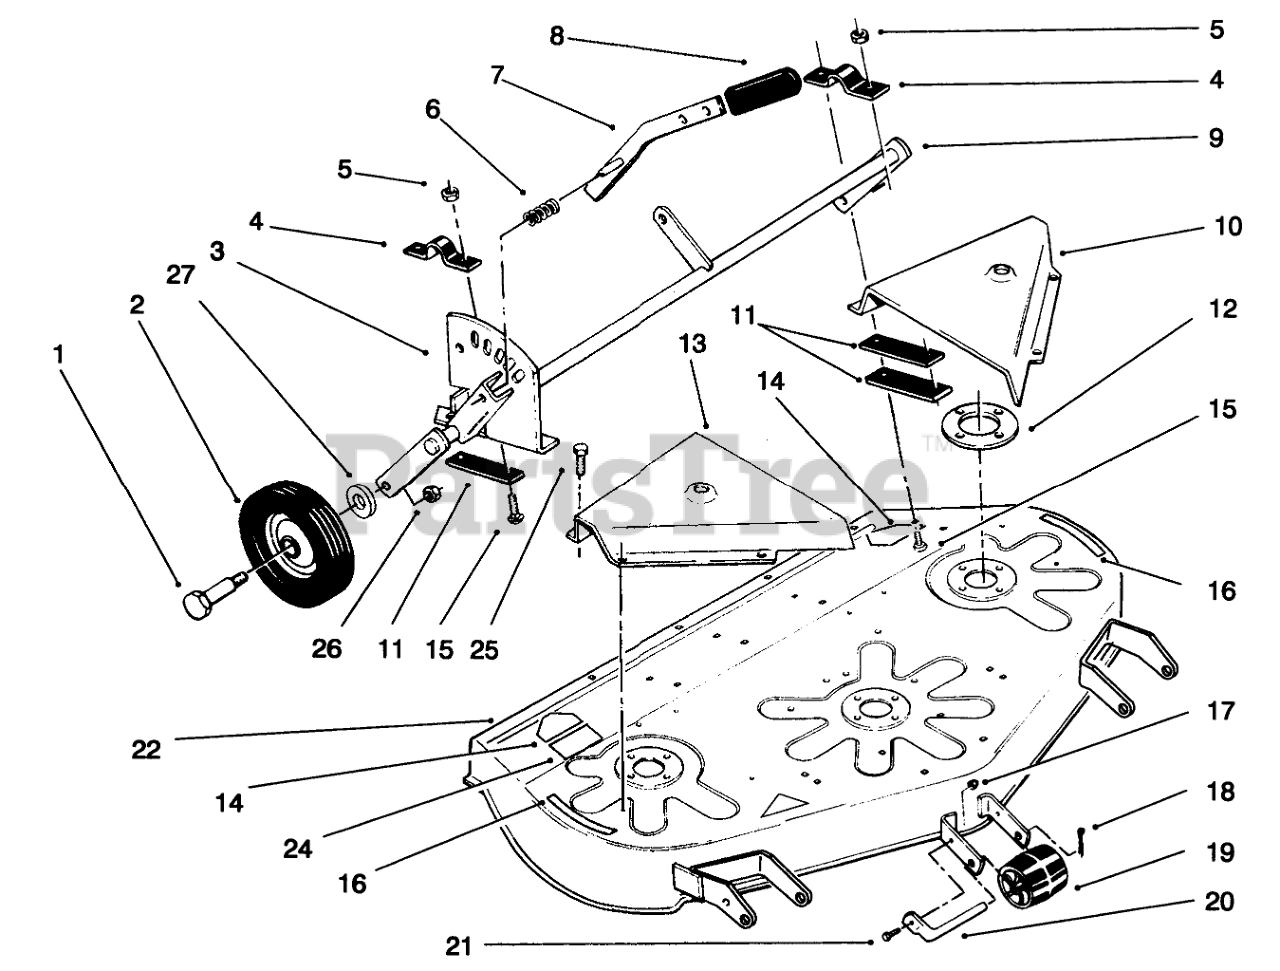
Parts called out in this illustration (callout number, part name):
1	BOLT-SHOULDER
2	WHEEL ASM
3	Quadrant
5	NUT-LOCK, NI
6	SPRING-COMPRESSION
7	Lever
9	Gauge-Wheel Support
10	Belt Cover LH
11	Bar
12	PLATE-SPINDLE
13	Belt Cover RH
14	DECAL-DANGER
15	BOLT-CARR
16	DECAL-DANGER
17	NUT-LOCK, NI
18	PIN-COTTER
19	ROLLER ASSY
20	ROLLER-SHAFT
21	SCREW-HH
22	Deck-Mower (Incl. Ref. #14 & 16)
24	DECAL-HEIGHT & BELT
25	Bolt
26	NUT-HEX
27	WASHER
